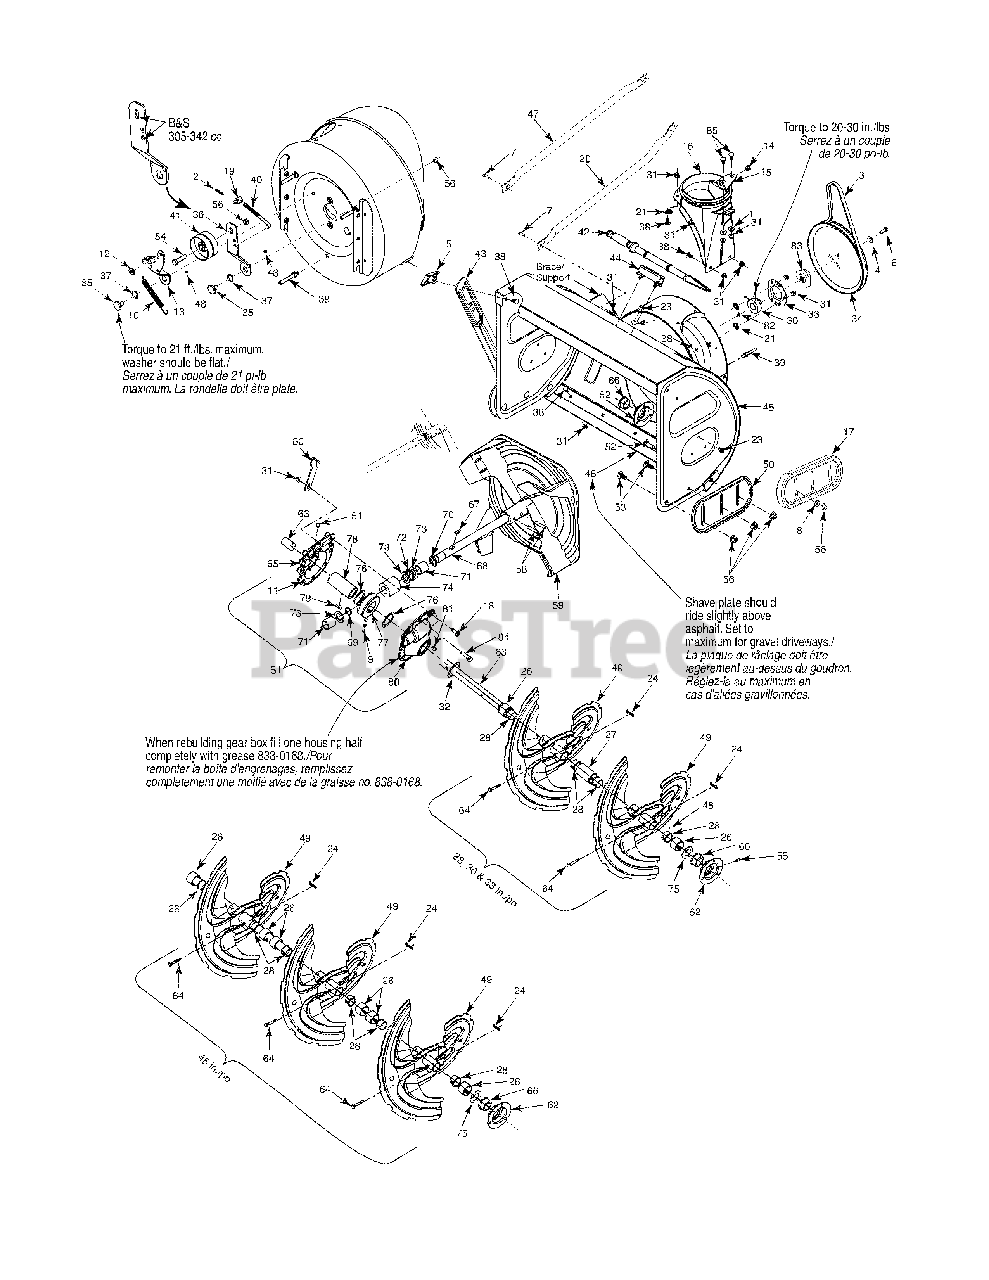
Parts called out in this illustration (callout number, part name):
1	Flat Washer .349 ID x .879 OD x .063
2	Int. Cotter Pin
3	V-Belt 1/2 x 44" Lg.
3	V-Belt 1/2 x 42" Lg.
4	Flat Washer .34 x 1.5 x .150
5	Handle Knob Assembly
6	Hex Screw 5/16-24 x .875 Gr. 8 Lock
7	Hex Hd Cap Scr. 5/16-18 x .75 Gr. 5
8	Flat Washer .385 x .870 x .092
9	Shell Alvania Grease (3 oz.)
10	Extension Spring .470 Dia. x 4.75
11	Ultra Grey Loctite #5699
12	Flat Washer .344 ID x .75 OD x .120
13	Brake Bracket Ass’y (900 Series)
14	Plastic Bushing .380 ID
16	Chute Adapter
17	Reversible Slide Shoe (Plastic)
18	Screw, 5/16-18 x .5
19	Adjustment Ferrule
21	Push-on Nut .25 diam
23	Hex TT Screw 5/16-18 x .75
24	Bow Tie Cotter Pin
26	Spacer 1.5 x 1.0 ID x 1.0" Lg.
27	Spacer 1.5 x 1.0 ID x 2.5" Lg.
28	Flange Bushing 1.05 ID x 1.16 OD
30	Self-Aligning Bearing .875 ID
31	Hex Flg. L-Nut 5/16-18 Gr. F Nylon
32	Flat Washer 1.010 x 1.88 x .060
33	Bearing Housing
34	Pulley .5 ID x 10 OD
35	Shoulder Scr .625 Dia x .170
36	Auger Idler Bracket
37	Wave Washer .625 ID x .885 OD x .015
38	Carriage Bolt 5/16-18 x .75
39	Screw 5/16-18 x .43 (w/stud)
40	Auger Idler Rod
41	Flat Idler Pulley
42	Cleanout Tool
44	Cleanout Tool Mount
45	Standard Housing*, 28"
51	Worm Gear Box Ass’y (w/o grease fitting)
51	Worm Gear Box Ass’y (w/ grease fitting)
52	Carriage Bolt 3/8-16 x 1.00" (w/steel shoe)
52	Carriage Bolt 3/8-16 x 1.25" (w/plastic shoe)
53	Carriage Bolt 3/8-16 x .75" (w/steel shoe)
53	Carriage Bolt 3/8-16 x 1.00" (w/plastic shoe)
54	Hex Hd. Cap Scr 3/8-16 x 1.75 Gr. 5
55	Grease Fitting
56	Hex Flange L-Nut 3/8-16 Gr. F Nylon
58	Spring Spirol Pin Heavy - 5/16 dia x 1.7
63	Auger shaft, 28"
63	Auger shaft, 30"
63	Auger shaft, 33"
63	Auger shaft, 45"
64	Shear Pin 5/16-18 x 1.75
65	Gear Housing Half - RH
66	Flange Bearing
67	#9 HI-Pro Key 3/16 x 3/4 Dia HT
68	Auger Drive Shaft
69	Snap Ring for .875 dia. shaft
70	Oil seal for .875 ID Garlock (76 x 6133)
71	Sleeve Bearing .875 ID
72	Thrust Bearing .88 ID x 1.44 OD x .078
73	Flat Washer .88 ID x 1.4 OD x .125
74	Worm Gear LH Double Thread
75	Spacer
76	Flat Washer 1.5 ID x 2.0 OD x .03
77	Worm Gear LH Double Thread (Bronze)
78	Worm Gear Shaft
79	#91 Woodruff Key 1/4 x 3/4 Dia.
80	Gear Housing Half LH
80	Gear Housing Half LH (w/grease fitting hole)
81	#91 Woodruff Key 1/4 x 3/4 Dia.
82	Low Temperature grease
83	Pulley Adapter .75 Dia. w/pins
84	Hex Hd. Cap Scr. 5/16-18 x 1.0 Gr. 5
85	Carriage Bolt 5/16-18 x 1.00" Lg
05845C-0665	HOUSING BEARING - YARDMAN GREEN (0665)
